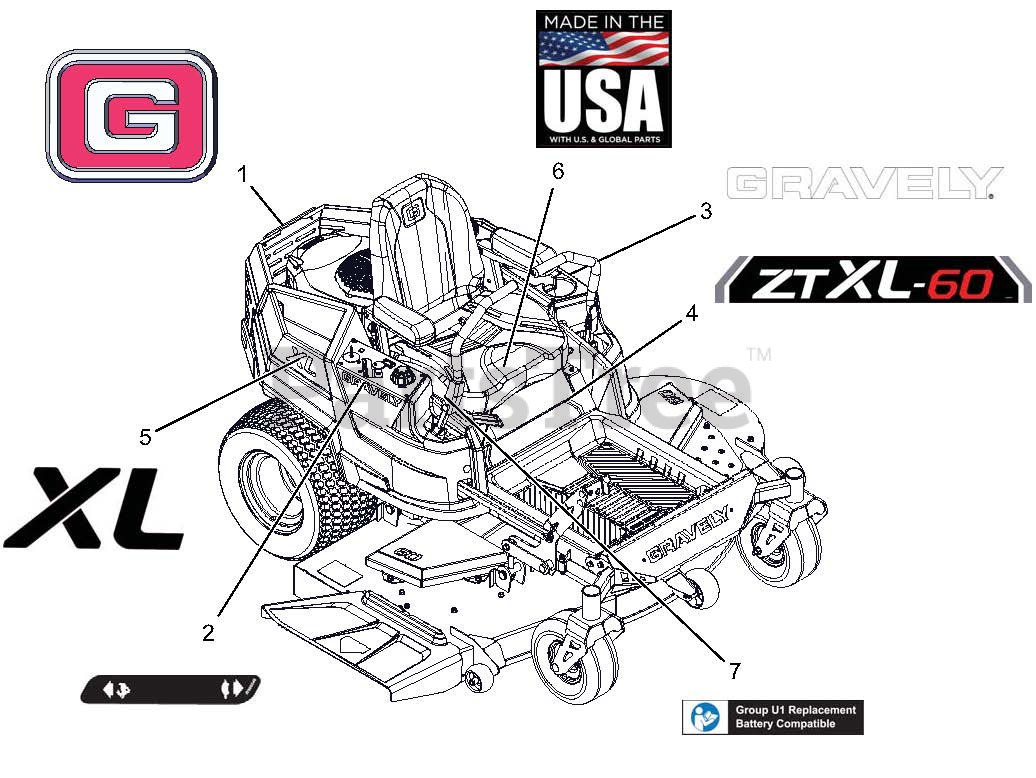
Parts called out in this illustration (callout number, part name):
1	DECAL, GRAVELY BRAND
2	DECAL, DASH DECAL
3	DECAL, 9.5" GRAVELY LOGO
4	DECAL, ZTXL 60
5	DECAL, "XL"
6	DECAL, MADE IN USA
7	DECAL, U1 BATTERY REPLACEMENT
